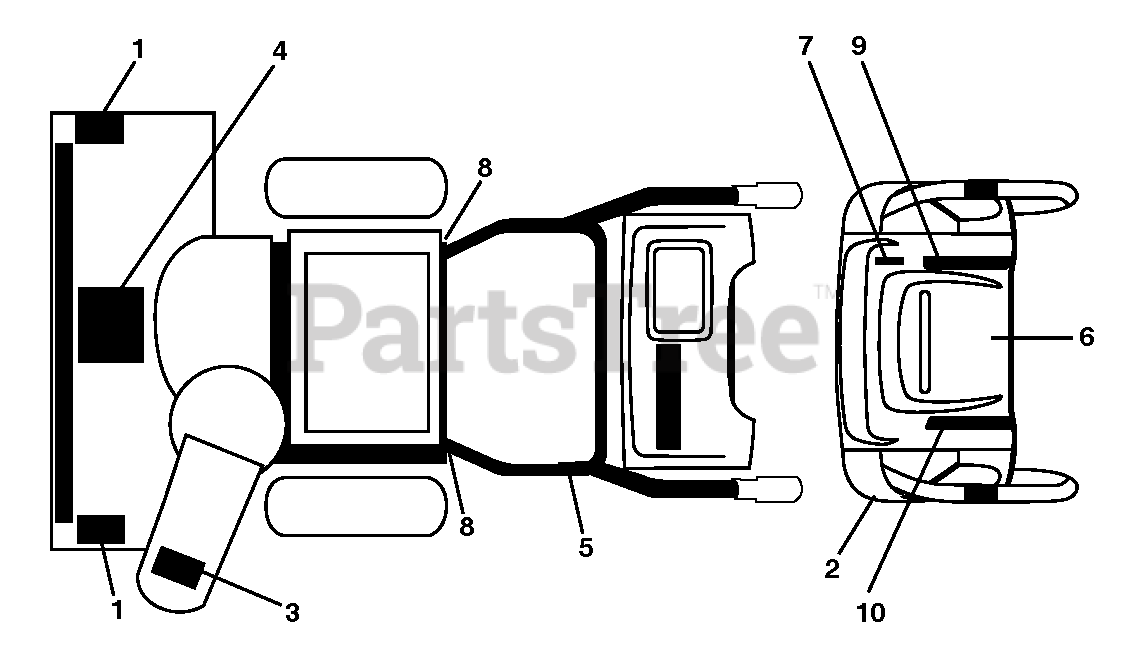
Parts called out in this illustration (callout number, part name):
1	DECAL.AUGER.SAFETY.
2	DECAL,HEIGHTADJUST
3	DECAL.CHUTE.SAFETY.
4	DECAL.AUGER."
5	DECAL.NOISE.LEVEL.105DB/CE.EAC
7	DECAL.CONSOLE.HAND.WARMER
8	DECAL.BELT.GUARD.
9	DECAL CONSOLE DECAL DECAL.SNOW
10	DECAL CONSOLE DECAL DECAL.SNOW
